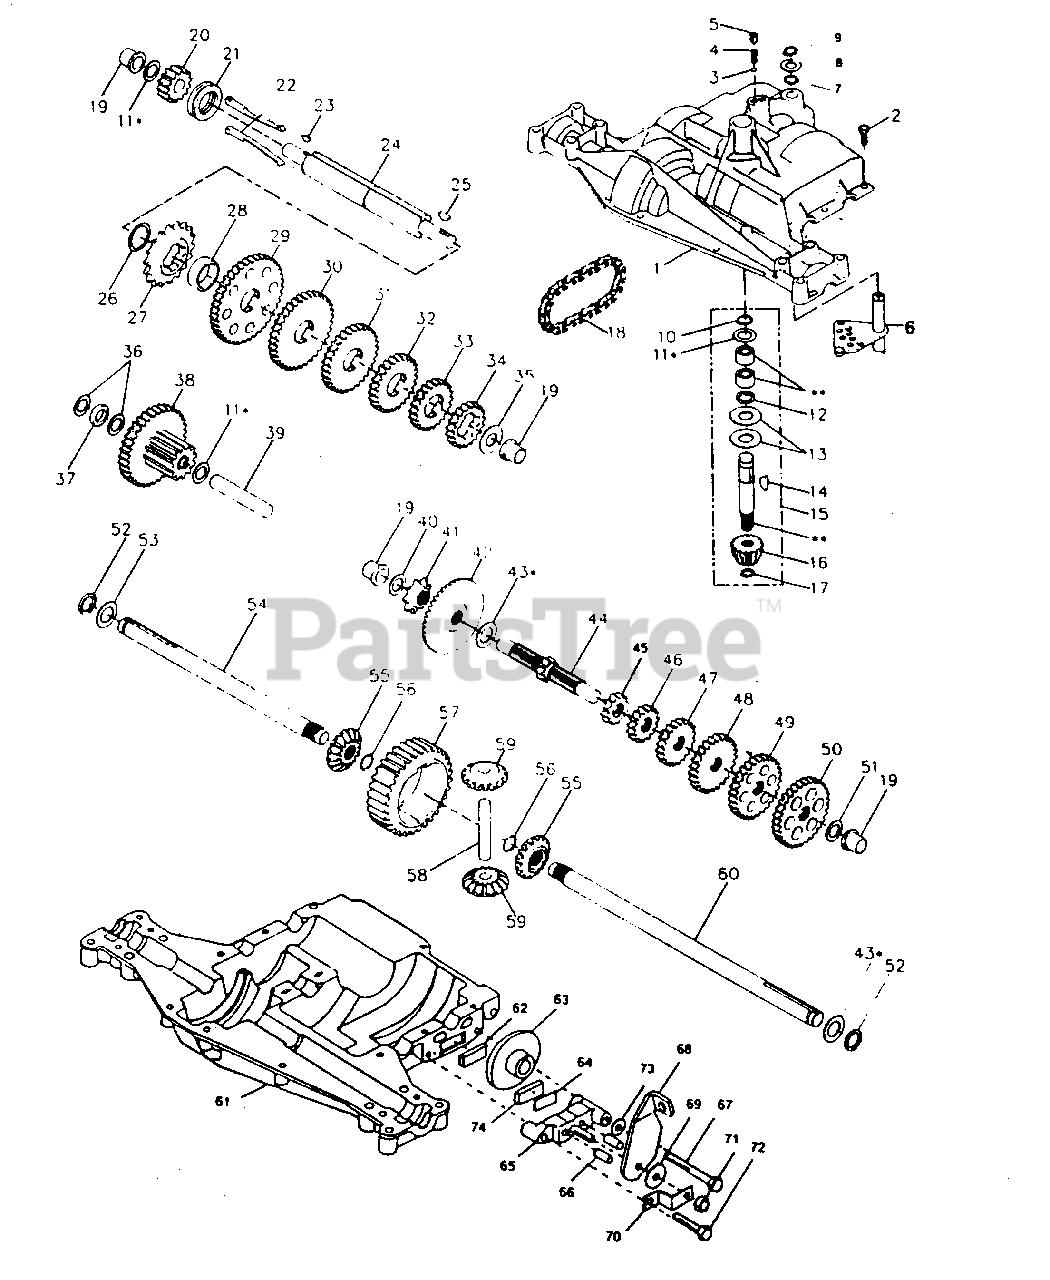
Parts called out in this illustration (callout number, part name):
1	Upper Housing (Dana part number)
2	Tapping Screw (Dana part number)
3	Detent Ball (Dana part number)
4	Detent Spring (Dana part number)
5	Set Screw (Dana part number)
6	Shifter Assembly (Dana part number)
7	O-Ring (Dana part number)
8	Plain Washer .505 x .942 x .006 (Dana part number)
8	Plain Washer .505 x .942 x .010 (Dana part number)
8	Plain Washer .505 x .942 x .015 (Dana part number)
8	Plain Washer .505 x .942 x .020 (Dana part number)
8	Plain Washer .505 x .942 x .026 (Dana part number)
8	Plain Washer .505 x .942 x .030 (Dana part number)
8	Plain Washer .505 x .942 x .040 (Dana part number)
9	Retaining Ring (Dana part number)
10	Retaining Ring (Dana part number)
11	Plain Washer .632 x 1.00 x .010 (Dana part number)
11	Plain Washer .632 x 1.00 x .020 (Dana part number)
11	Plain Washer .632 x 1.00 x .026 (Dana part number)
11	Plain Washer .632 x 1.00 x .031 (Dana part number)
11	Plain Washer .632 x 1.00 x .036 (Dana part number)
11	Plain Washer .632 x 1.00 x .041 (Dana part number)
11	Plain Washer .632 x 1.00 x .046 (Dana part number)
11	Plain Washer .632 x 1.00 x .050 (Dana part number)
11	Plain Washer .632 x 1.00 x .060 (Dana part number)
11	Plain Washer .632 x 1.00 x .082 (Dana part number)
12	O-Ring (Dana part number)
13	Plain Washer
14	#9 Woodruff Key
15	Input Shaft Assembly Kit (Dana part number)
16	14T Bevel Pinion (Dana part number)
17	Retaining Ring (Dana part number)
18	24 Pitches Chain (Dana part number)
19	Flange Bearing (Dana part number)
20	14T Spur Gear
21	Clutch Collar (Dana part number)
22	Clutch Key (Dana part number)
23	Woodruff Key
24	Intermediate Shaft (Dana part number)
25	#61 Woodruff Key (Dana part number)
26	Retaining Ring (Dana part number)
27	18T Sprocket (Dana part number)
28	Spacer (Dana part number)
29	37T Spur Gear
30	35T Spur Gear
31	30T Spur Gear (Dana part number)
32	25T Spur Gear
33	22T Spur Gear (Dana part number)
34	19T Spur Gear (Dana part number)
35	Plain Washer (Dana part number)
36	Plain Washer .632 x 1.00 x .026 (Dana part number)
37	Spacer (Dana part number)
38	Comb. Gear Assembly (Dana part number)
39	Spacer (Dana part number)
41	9T Sprocket (Dana part number)
42	42T Bevel Gear (Dana part number)
43	Plain Washer .758 x 1.12 x .010 (Dana part number)
43	Plain Washer .758 x 1.12 x .015 (Dana part number)
43	Plain Washer .758 x 1.12 x .020 (Dana part number)
43	Plain Washer .758 x 1.12 x .025 (Dana part number)
43	Plain Washer .758 x 1.25 x .020(Dana part number)
43	Plain Washer .758 x 1.25 x .025 (Dana part number)
43	Plain Washer .758 x 1.25 x .031 (Dana part number)
43	Plain Washer .758 x 1.25 x .035 (Dana part number)
43	Plain Washer .758 x 1.25 x .040(Dana part number)
43	Plain Washer .758 x 1.25 x .045 (Dana part number)
43	Plain Washer .758 x 1.25 x .050 (Dana part number)
43	Plain Washer .758 x 1.25 x .055 (Dana part number)
43	Plain Washer .758 x 1.25 x .062 (Dana part number)
44	Drive Shaft (Dana part number)
45	12T Spur Gear (Dana part number)
46	15T Spur Gear (Dana part number)
47	20T Spur Gear (Dana part number)
48	25T Spur Gear (Dana part number)
49	28T Spur Gear (Dana part number)
50	31T Spur Gear (Dana part number)
51	Plain Washer (Dana part number)
52	Felt Seal (Dana part number)
53	Plain Washer (Dana part number)
54	L.H. Axle (Dana part number)
55	15T Miter Gear
56	Retaining Ring (Dana part number)
57	32T Spur Gear (Dana part number)
58	Cross Shaft (Dana part number)
59	15T Miter Gear
60	R.H. Axle (Dana part number)
61	Lower Housing (Dana part number)
62	Friction Puck (Dana part number)
63	Brake Disc(Dana part number)
64	Spacer (Dana part number)
65	Brake Jaw (Dana part number)
66	Dowel Pin (Dana part number)
67	Tapping Screw (Dana part number)
68	Actuating Lever
69	Plain Washing
70	Anti-Rotation Bracket (Dana part number)
71	Lock Nut (Dana part number)
72	Tapping Screw(Dana part number)
73	Plain Washer
74	Friction Puck (Dana part number)
75	Grease (Dana part number)
